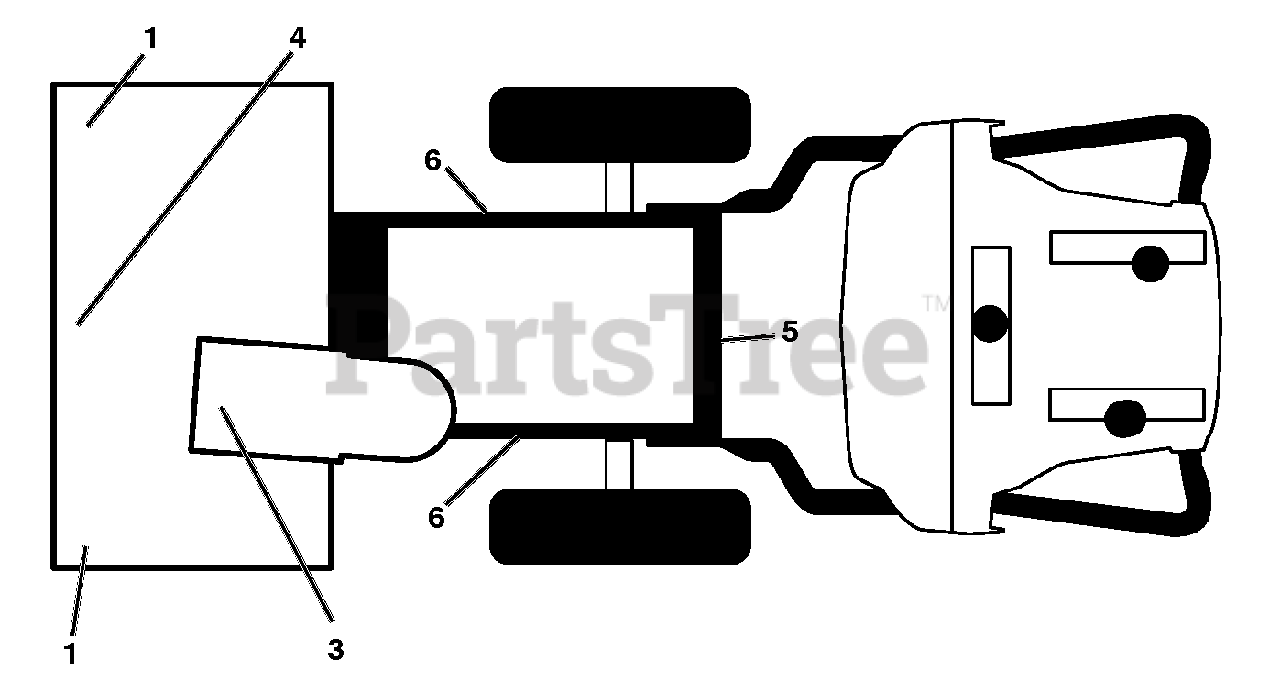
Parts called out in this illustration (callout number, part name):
1	DECAL.AUGER.SAFETY.
3	DECAL.CHUTE.SAFETY.
4	DECAL.AUGER."
5	DECAL.BELT.GUARD.
6	DECAL.FENDER
